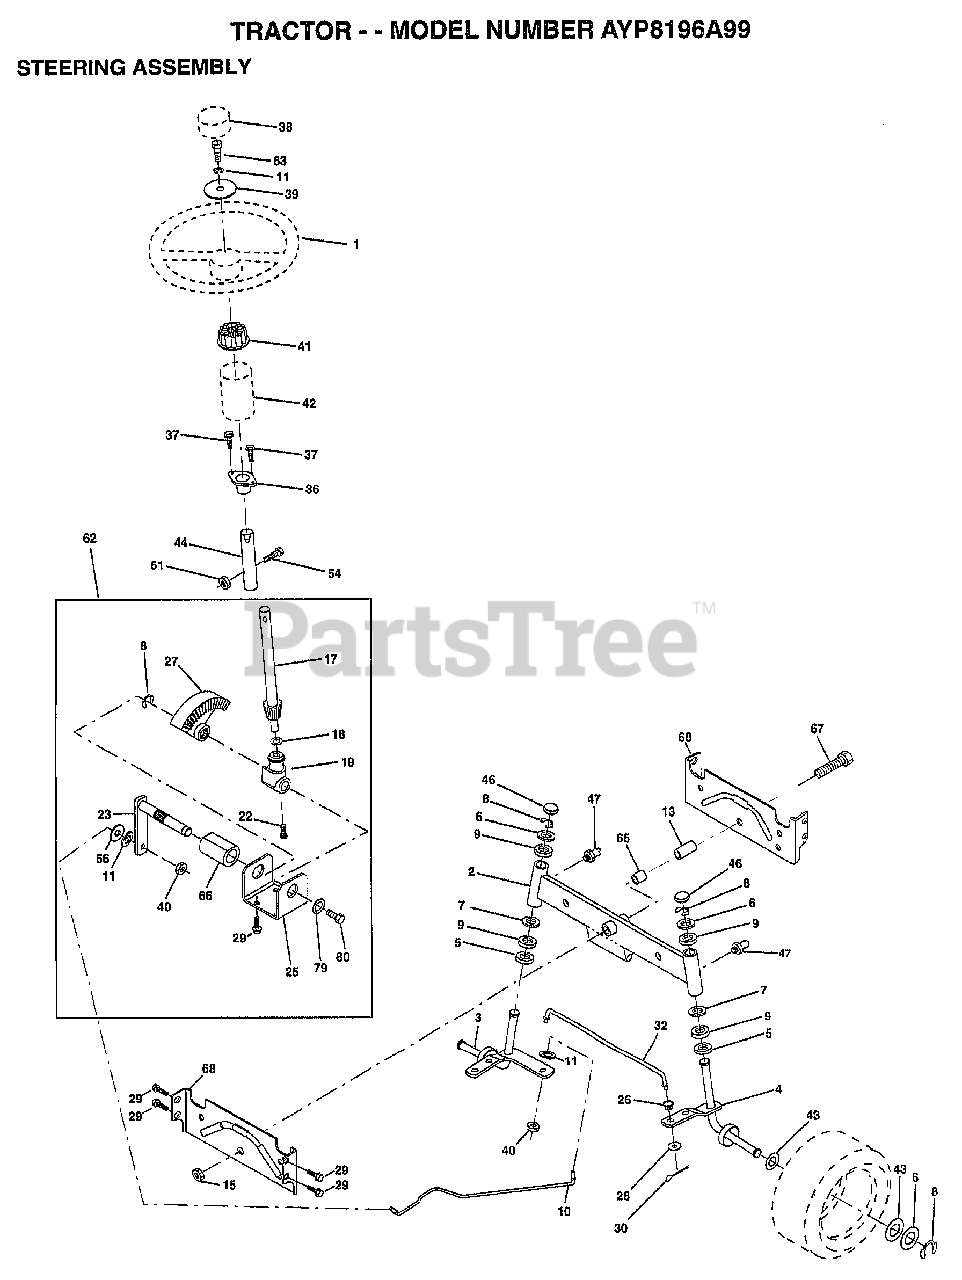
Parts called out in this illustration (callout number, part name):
1	WHEEL STR AYP BLK
2	AXLE ASM
3	"SPINDLE ASM,RH"
4	"SPINDLE AMS,LH"
5	WASHER .T
6	WASHER
7	WASHER
8	RING
9	COL. SRTG. BEAR.
10	DRAGLINK-STAMPED
11	LOCKWASHER
13	BEARING AXLE
15	"NUT-LOC,FLANGE LT"
17	SHAFT ASM STEERIN
18	THRUST WASHER
19	SUPPORT.SHAFT.STEER
22	SCREW.HX.WSH.HD
23	SHAFT.ASM.PITMAN
25	BRKT-STEERING
26	BUSHING.DRAGLINK
27	GEAR SECTOR
28	WASHER
29	SCREW
30	COTTER PIN
32	TIE ROD
36	BUSHING.STEERING
37	"SCREW-TT,10-32 FL"
38	CAP STEER AYP
39	WASHER T
40	GRIPCO NUT
41	ADAPTER LT
42	BOOT.STEER.PL
43	WASHER
44	EXT SHAFT STEERIN
46	CAP
47	ZERK M
51	NUT
54	BOLT
56	WASHER
62	KIT.STEER.ASM
63	BOLT
65	SPACER AXLE
66	"BEARING-ARM,PITMA"
67	BOLT
68	BRACE AXLE
79	WASHER
80	BOLT.HX.NYLON3/8-16X3/
